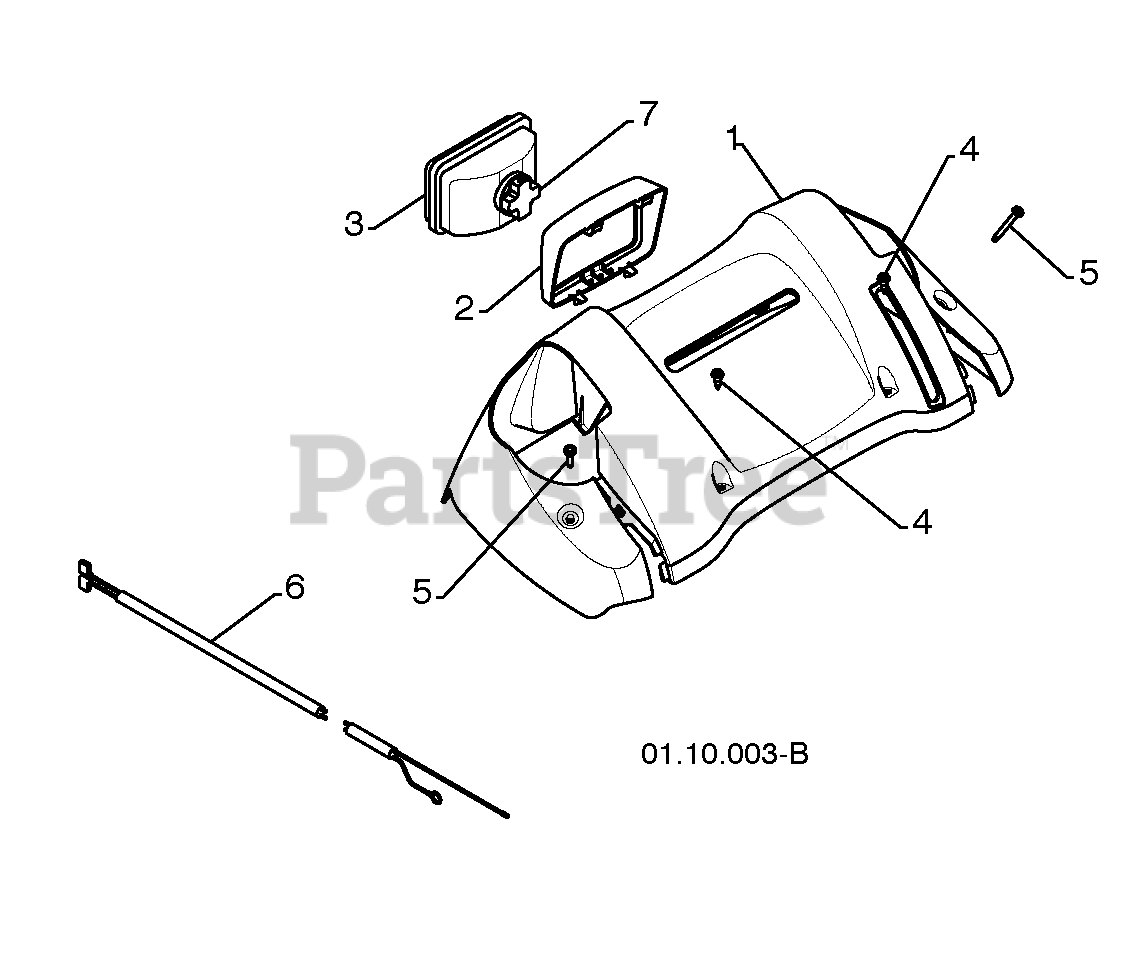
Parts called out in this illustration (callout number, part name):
1	CONSOLE PANEL
2	HEADLIGHT BEZEL
3	FLOOD HEADLIGHT
4	SCREW 10-24 X .625
5	SCREW 10-24 X 1.25
6	WIRE HARNESS
7	BULB
